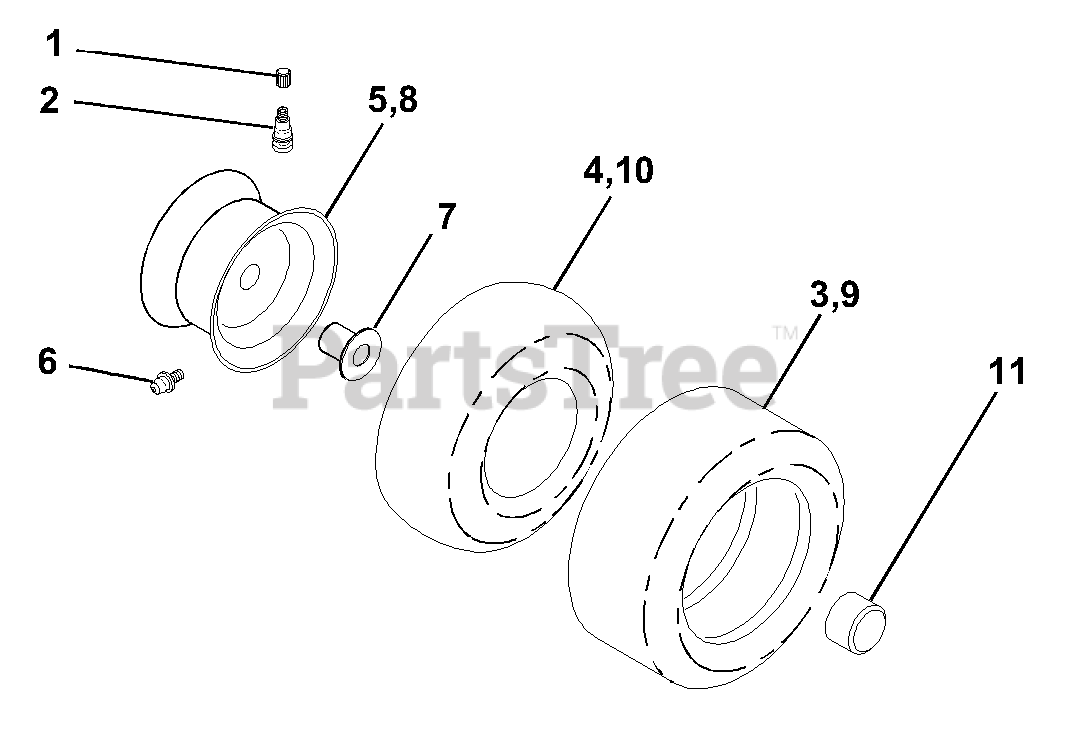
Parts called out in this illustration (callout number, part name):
1	Cap Valve Tire
2	Stem Valve
3	Tire F Ts 15 X 6 0 - 6 Service
4	Tube Front
5	Rim Asm 6" front White Service
6	Fitting Grease
7	Bearing Flange
8	Rim Asm 8" rear White Service
9	Tire R Ts 18 x 8.5-8 C Service
10	Tube Rear
11	Cap Axle Blk 1 50 X 1 00
